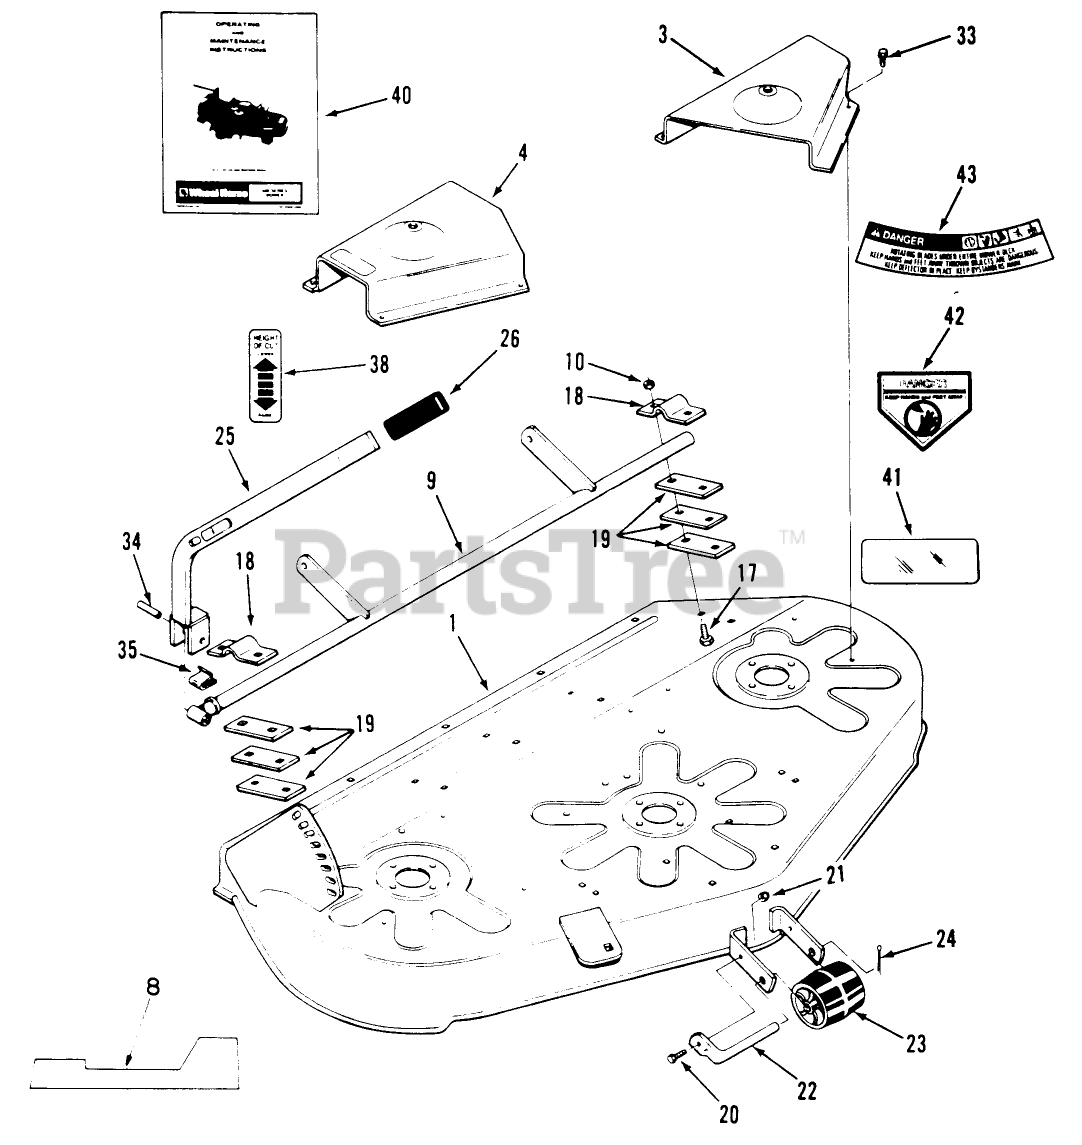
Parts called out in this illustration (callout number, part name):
1	Deck-Mower
3	Belt Cover LH
4	Belt Cover RH
8	DECAL-42" RECYCLER
9	Lift Support
10	NUT
17	Bolt
19	Bar
20	Bolt
21	Nut
22	Roller Shaft
23	Roller
24	Cotter Pin
25	Lever
33	Bolt
34	SPIROL PIN 3/8X1 1/2
35	CLIP-SPRING
38	DECAL-HOC
40	OPERATOR'S-MANUAL
41	DECAL-OVERLAY
42	DECAL-DANGER
43	DECAL - DANGER
